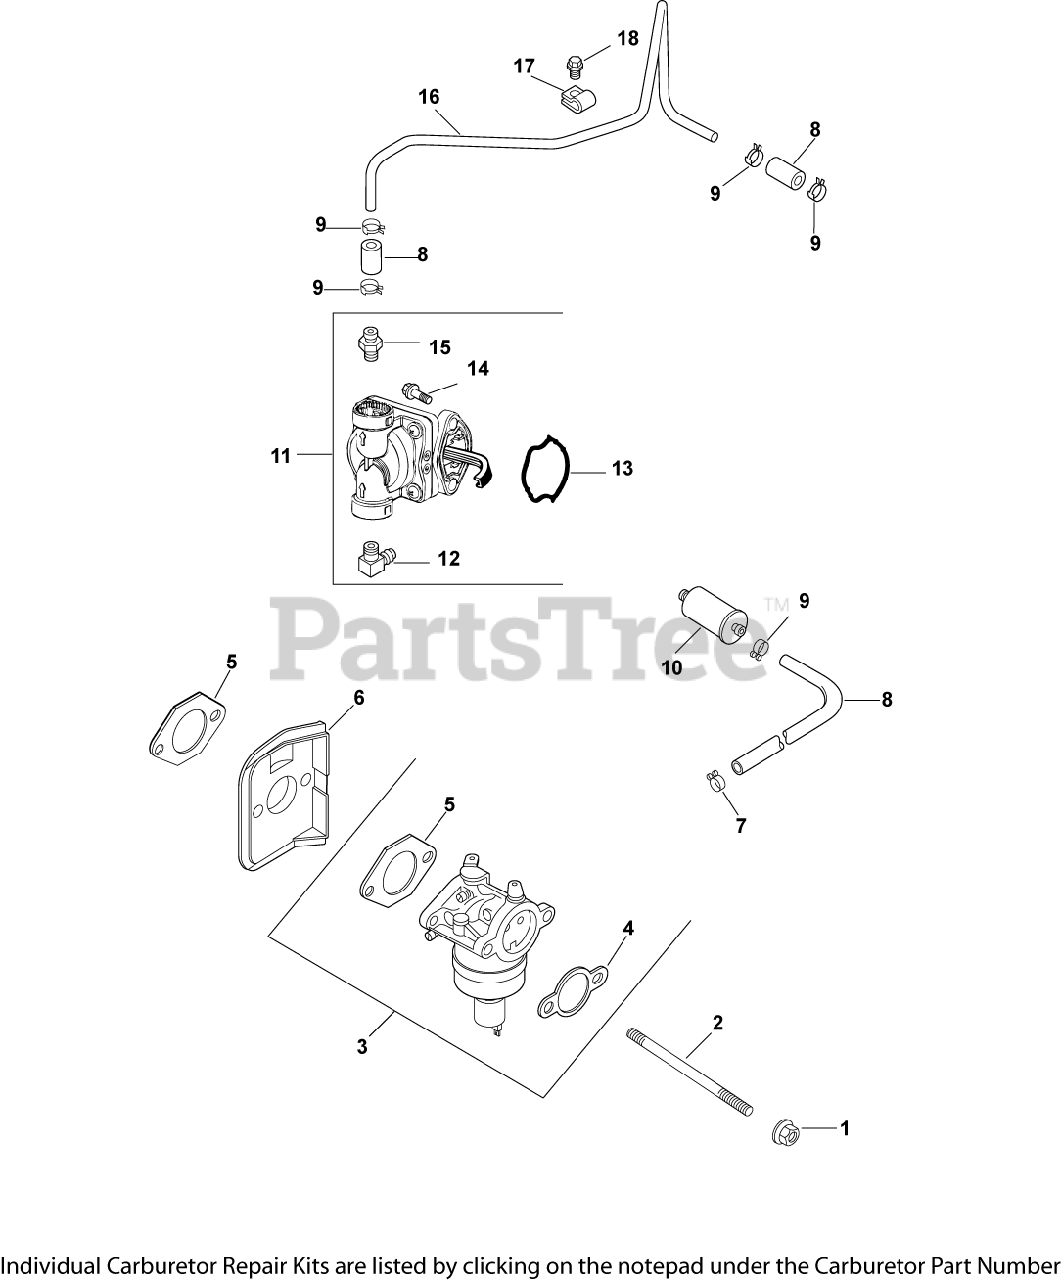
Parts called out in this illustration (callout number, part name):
1	NUT, FLG M6X1.0
2	STUD,M6X1.0X116
3	KIT, CARB W/GASKETS - USE 12 853 169-S
4	GASKET, AIR CLEANER BASE
5	GASKET, CARBURETOR
6	DEFLECTOR, HEAT
7	CLAMP, BAND SPRING HOSE-(#2523737S)
8	HOSE,LW PERM.FUEL 24.00"-USE 25 111 81-S
9	CLAMP, HOSE (KM)-USE 25 237 31-S
10	FILTER,FUEL 51 MICRON (FUEL PUMP)
11	KIT, FUEL PUMP
12	CONNECTOR, 90 DEG. HOSE
13	O-RING, FUEL PUMP
14	SCREW, LBD SKT M6x1.0x20-(#25086403S)
15	KIT, STRAIGHT FITTING
16	LINE, FUEL - DISCONTINUED
17	CLIP, TUBE & WIRING (KM)
18	SCREW, FLG THD FRM M5X.8X10
